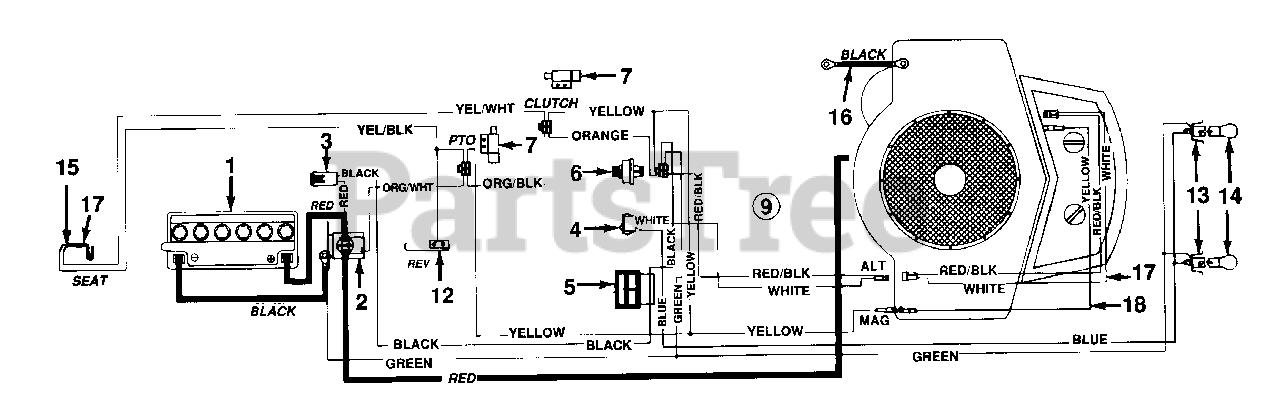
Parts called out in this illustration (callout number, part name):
1	Battery
2	Solenoid
3	Fuse 7.5 Amps
4	Light Switch
5	Ammeter
6	Ignition Switch
7	Safety Switch
9	Wire Harness
12	Safety Switch (Reverse)
13	Socket
14	Bulb (Headlight)
15	Safety Switch (Seat)
16	Ground Wire 7.5" Lg
17	Safety Switch (Seat)
18	Harness Adapter
